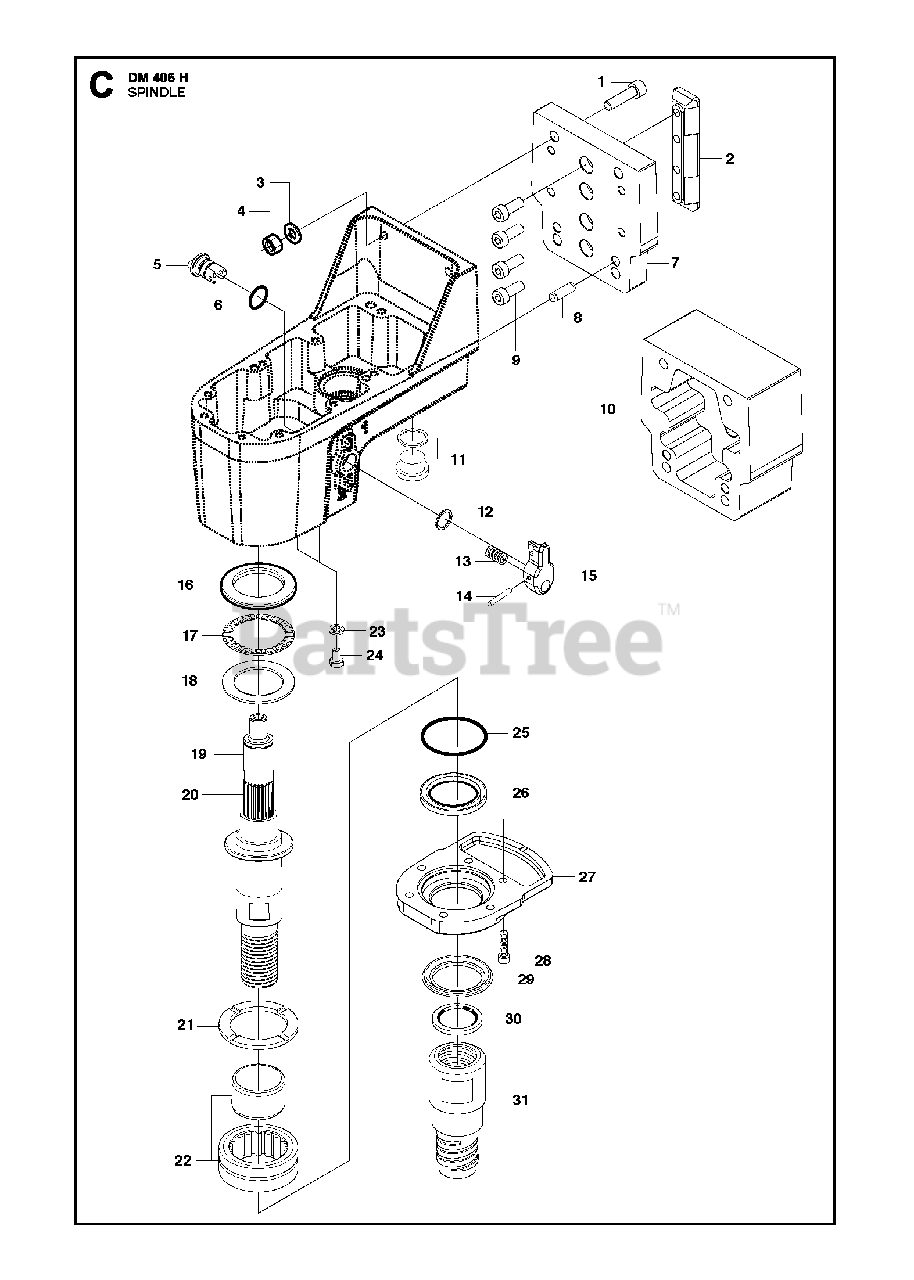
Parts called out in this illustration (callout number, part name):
3	WASHER
4	HEXAGON NUT
19	SPINDLE"1 1/4""-7 UNC"
20	SPINDLE CR 32 JAPANCR 32 for Japan
28	SCREW IHSCM
30	SEALING RINGOnly with CR28 thread
31	COUPLING"With CR28 thread fits on 1 1/4"" UNC"
